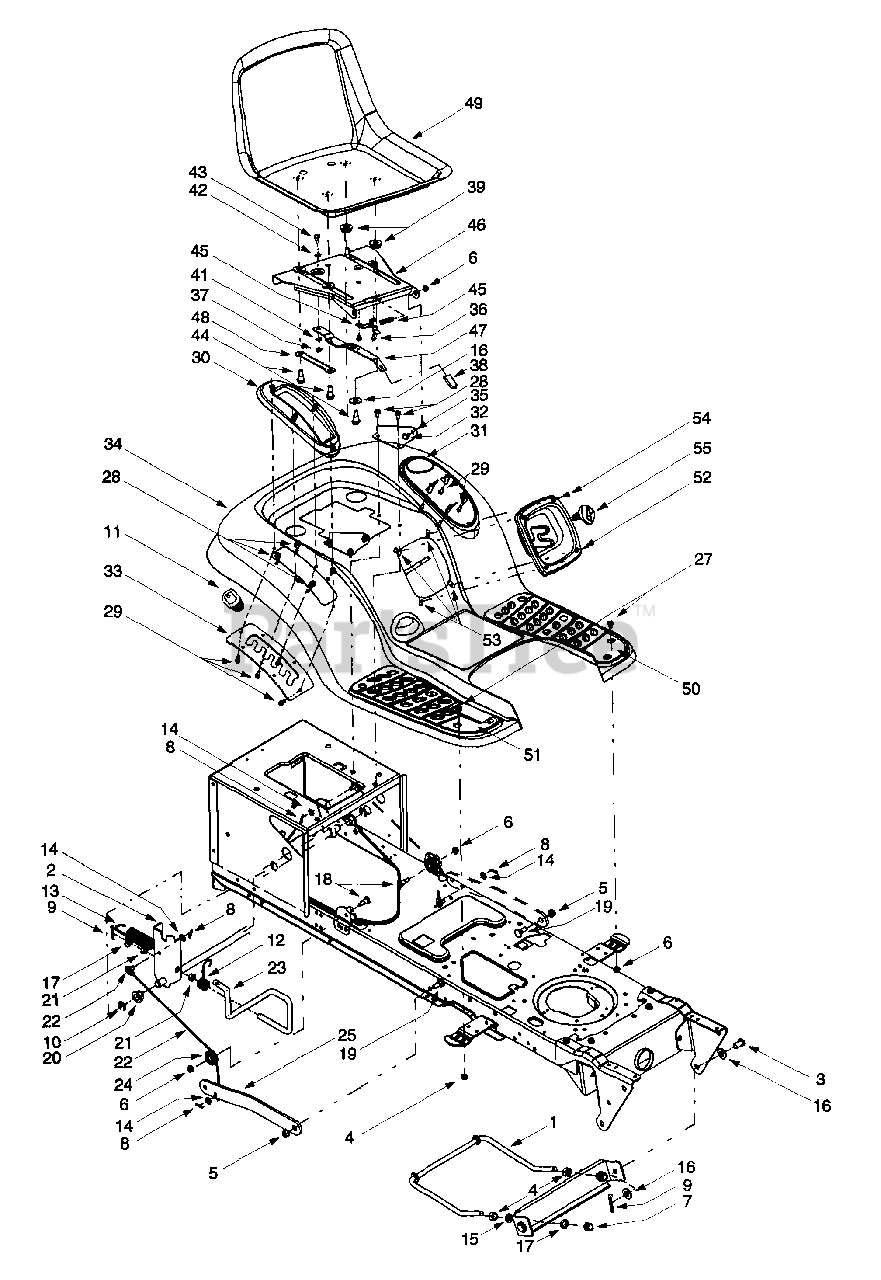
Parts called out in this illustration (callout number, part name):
1	Deck Stabilizer Rod
3	Clevis Pin, .5 x .78
4	Hex Nut, 1/2-13
5	Flange Lock Nut, 3/8-16
6	Flange Lock Nut, 5/16-18
7	Hex Nut, 1/2-13
8	Internal Cotter Pin
9	Cotter Pin
11	Handle Grip
12	Torsion Spring
13	Lift-assist Spring, 1.15 x 5.99
14	Flat Washer, 5/16
15	Lock Washer, 1/2
16	Flat Washer, .31 x 1.062 x .134
17	Flat Washer, .51 x 1.12 x .06
18	Hex Cap Screw, 5/16-18 x .62
19	Shoulder Screw, .5 x .27, 3/8-16
20	Hex Flange Bearing
21	Snap Flange Bearing
22	Lift Cable, 16.16
23	Lift Handle
24	Roller Pulley
27	Carriage Bolt, 5/16-18 x .62
28	Self Tapping Screw, 5/16-18 x .625
29	Self Tapping Screw, 1/4-15 x .75
30	Lift Lever Cover
31	Cover w/Cup Holder
32	Shoulder Screw, .437 x 1.62
36	Screw, #10-16 x .375
37	Hex Flange Lock Nut, 1/4-20
38	Seat Adjuster Grip
41	Spring Washer, .265 x .562 x .025
42	Flat Washer, .344 x .62 x .03
43	Shoulder Screw, .340 x .285,1/4-20
44	Shoulder Screw, .50 x .50, 3/8-16
45	Seat Stop
48	Seat Adjustment Selector
49	Seat, Black w/Drain Holes
50	LH Foot Pad
51	RH Foot Pad
52	Shift Cover
53	Speed Nut, 1/4-20
54	Phillips Screw, 1/4-20 x .75
55	Shift Knob
